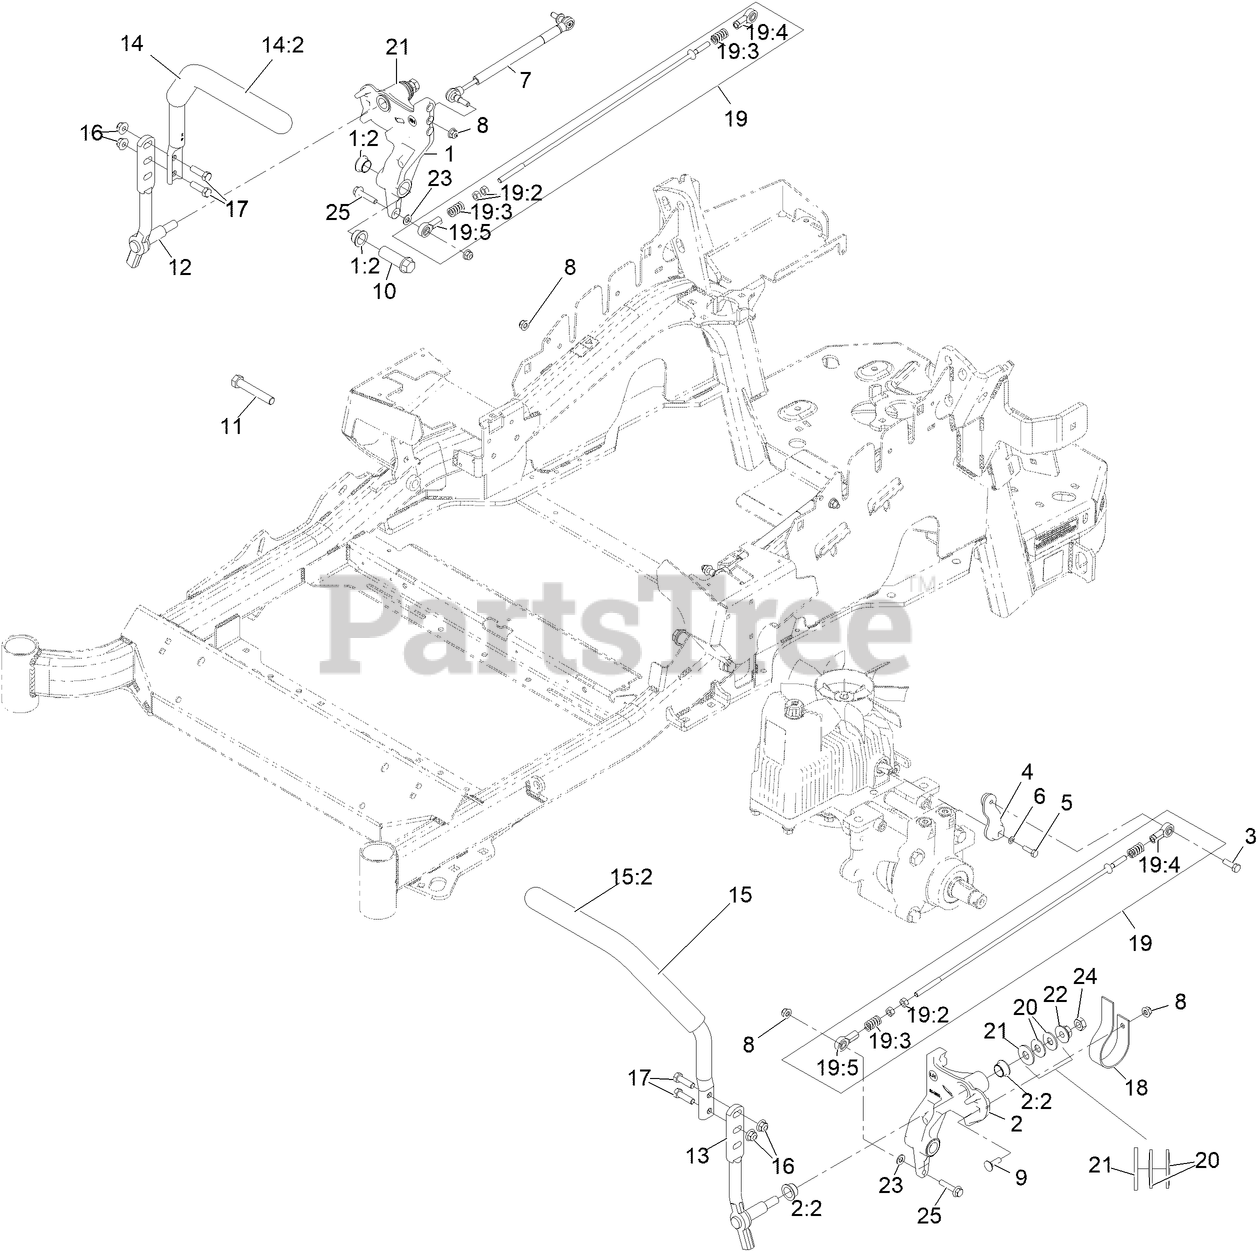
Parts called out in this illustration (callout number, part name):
1	RH MOTION CONTROL AND BUSHING ASM
1:2	BUSHING-FLANGE
2	LH MOTION CONTROL AND BUSHING ASM
2:2	BUSHING-FLANGE
3	SCREW-HH, THREAD LOCKING
4	ARM-CONTROL, PUMP
5	SCREW-HH
6	WASHER-SPRING
7	DAMPER-CONTROL, MOTION
8	NUT-HF, NI
9	BOLT-CARR
10	HUB-THREADED
11	SCREW-HH
12	LEVER-CONTROL MOTION, RH
13	LEVER-CONTROL MOTION, LH
14	ASM-HANDLE-RH
14:2	GRIP-CONTROL, LEVER
15	LH HANDLE ASM
15:2	GRIP-CONTROL, LEVER
16	NUT-HF, NI
17	SCREW-HH
18	SPRING-LEAF
19	PUMP LINKAGE REAR ASM
19:2	NUT-HEX
19:3	SPRING-COMPRESSION
19:4	BALLJOINT-LH
19:5	BALLJOINT-RH
20	WASHER-SPRING
21	WASHER-FLAT
22	NUT-HF
23	WASHER-PLAIN
24	NUT-JAM
25	SCREW-HHF
